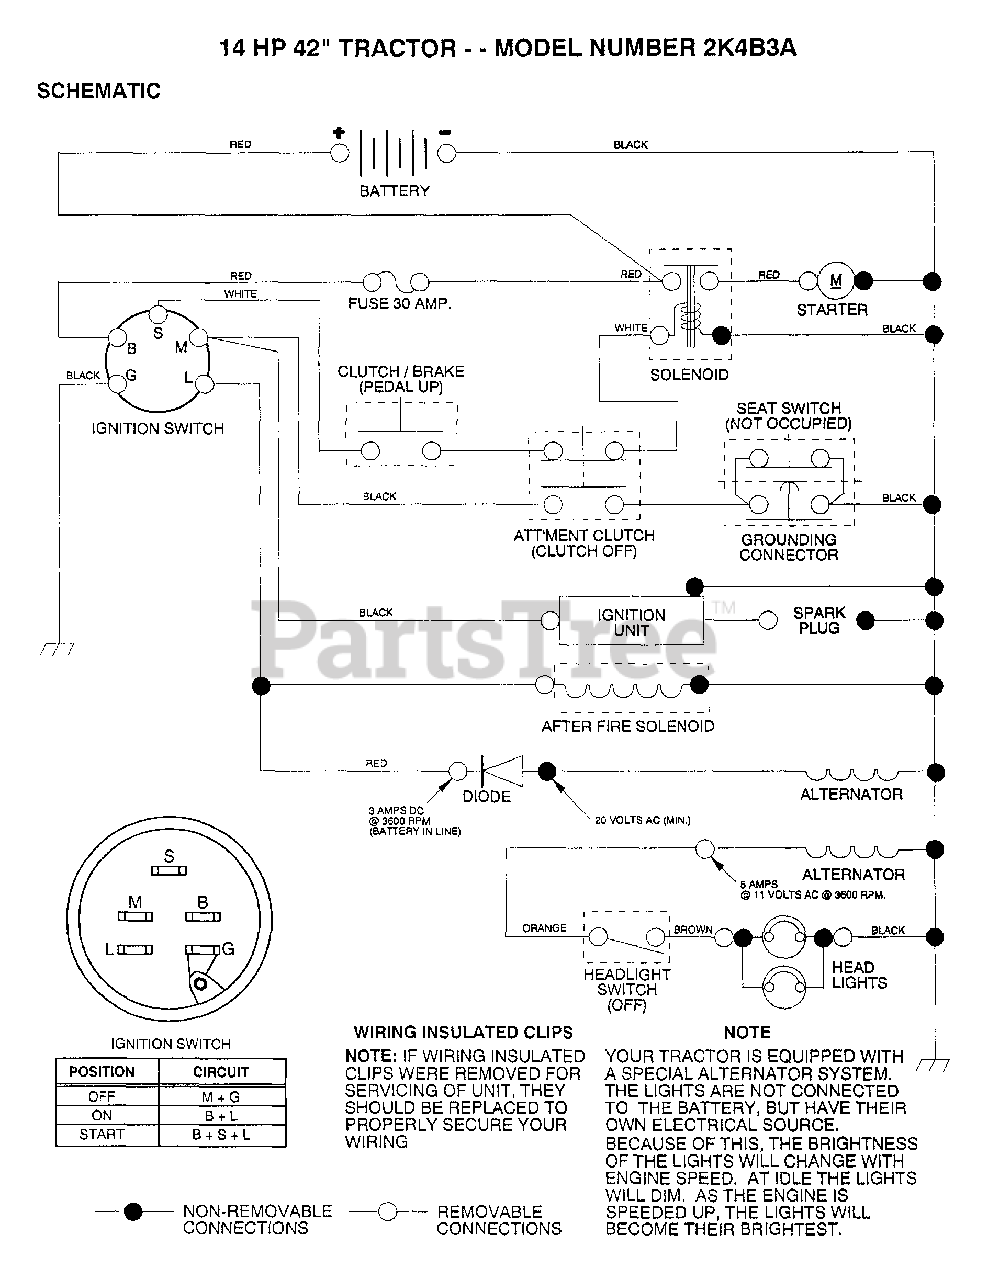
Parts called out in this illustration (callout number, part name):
4	"SPRING, DETENT LT"
5	"SCREW, SET LT"
6	KIT SHIFTER ASM
7	SHIFTER BOOT
8	SCREW TAP W/SEAL
9	SQUARE RING
10	RETAINING RING LT
11	ASM KIT SHIM 4689
12	"FLANGE, BEARING"
13	WASHER T
14	WOODRUFF KEY
15	AS KIT INPUT SHFT
16	PINION 14T T
17	"RING,RETAINING LT"
18	"CHAIN,24 PTCH LT"
19	BEARING.FLNG.5510
20	GEAR SPUR 14T
21	COLLAR CLUTCH
22	ASM KIT CLTCH KEY
23	NUT.LOCK.5/16-24
24	SHAFT INTERM
25	WOODRUFF KEY
26	"RING,RETAINING LT"
27	SPROCKET 18T T
28	SPACER YT
29	KIT.GEAR.12/37TH
32	GEAR 25T LT
33	GEAR SPUR 22 TT
34	SPUR GEAR 19T
35	"WASHER, PLAIN LT"
36	WASHER 025
36	ASSM GEAR COMB
37	SPACER
39	SHAFT IDLER
40	SPACER T
41	SPROCKET 9T LT
43	ASM KIT SHIM
44	SHAFT T
48	"GEAR, SPUR 25T LT"
49	GEAR 28T T
50	"GEAR, SPUR 31T LT"
51	WASHER 060
52	NEOPRENE WASHER
53	WASHER 031
55	GEAR 15T T
56	"RING,RETAINING LT"
58	SHAFT T
59	GEAR 1ST T
62	PUCK T
63	BRAKE DISC. T
64	SPACER LT
66	PIN T
69	WASHER LT
71	"SCREW, TAPPING LT"
72	PUCK T
